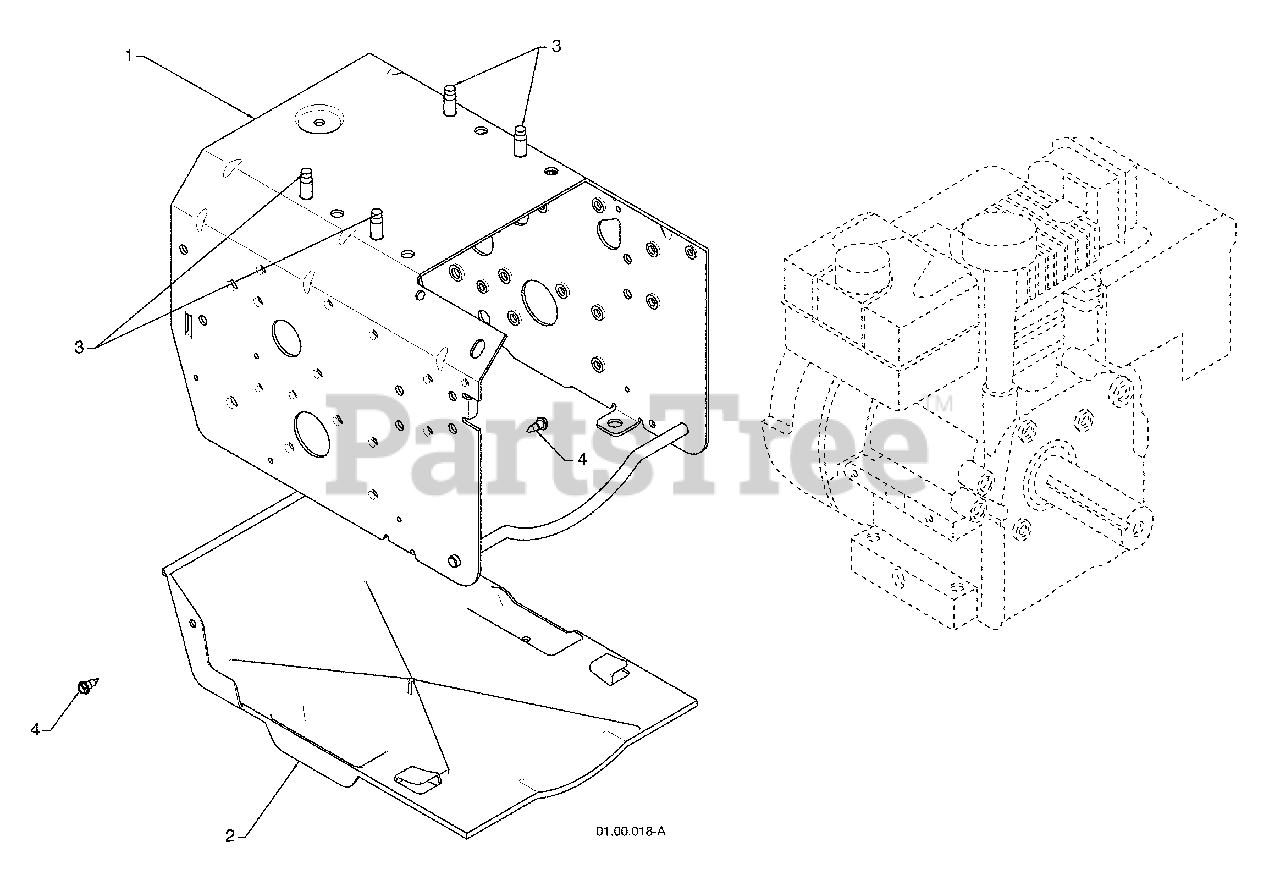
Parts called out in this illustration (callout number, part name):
2	BOTTOM PAN
3	BOLT 3/8-16
4	SCREW 10-24 X .625
